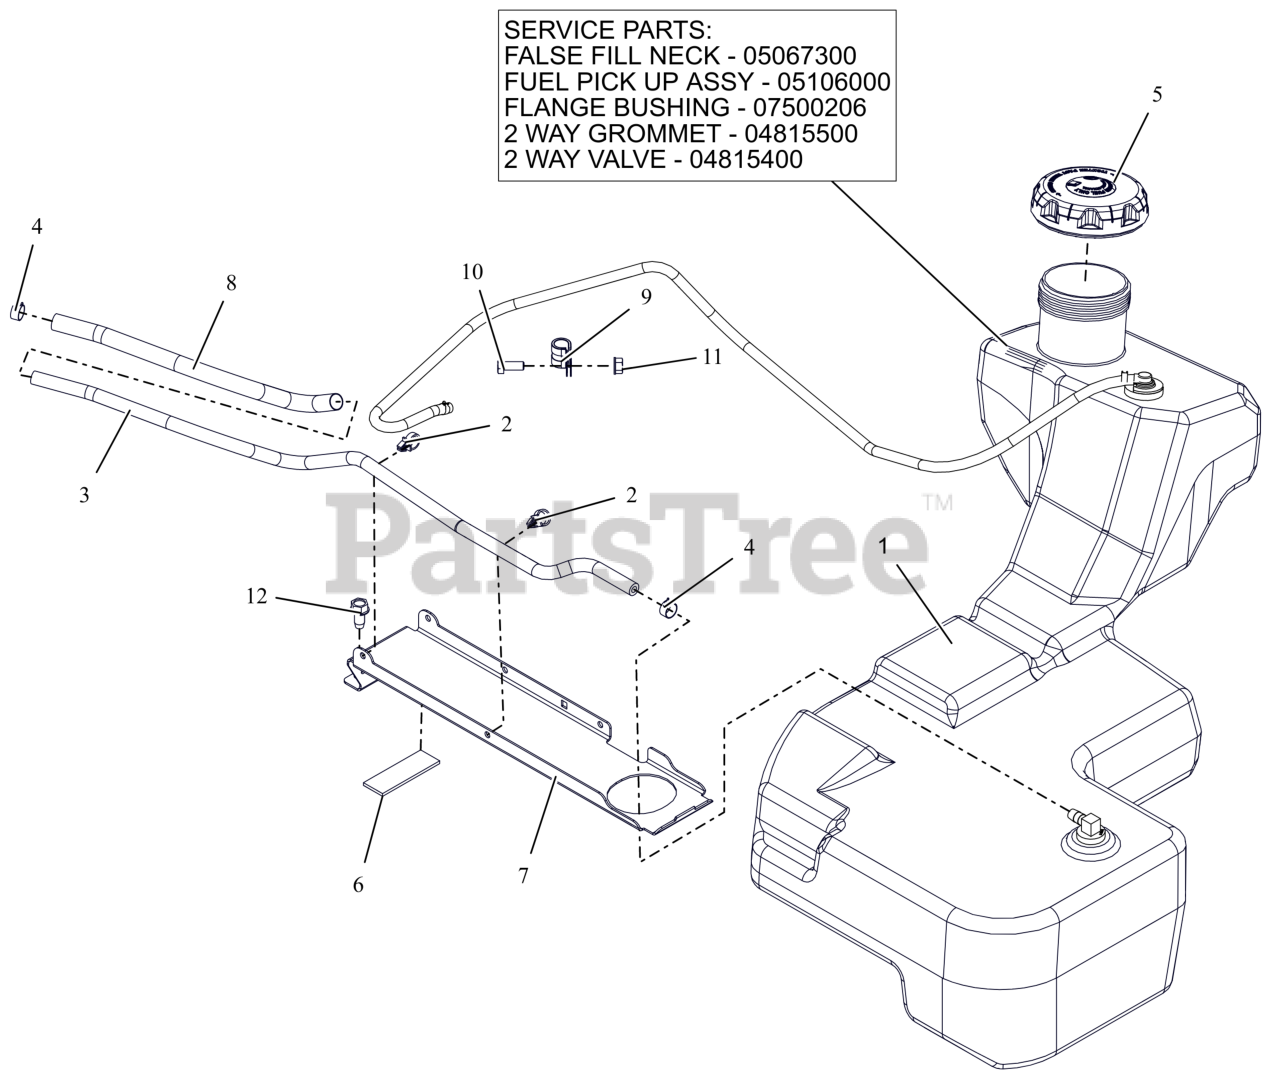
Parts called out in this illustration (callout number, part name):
1	ASM, FUEL TANK-HD
1	INSERT, FUEL NECK FALSE FILL
1	ASM, HD FUEL PICK-UP
1	BSHG-FLG .375X1.062X.625 NITR
1	GROMMET, 2-WAY
1	VALVE, 2-WAY
2	ROUTING CLIP (1/2" ID)
3	HOSE, .25 LOW-PERM BULK GAS
4	CLAMP, FUEL LINE
5	CAP, FUEL VENTIN AUTOLOCK
6	PAD,RBR 1.0"X3.0" W/ADHESIVE
7	BRKT, FUEL TANK HOLD DOWN
8	SLEEVE, THERMAL 12"
9	CLAMP, CUSHIONED STEEL
10	BLT,HEX .31-18X.75 G5 ZCC
11	NUT,LK-CTR-FLG .31-18 GF ZCC
12	SCR,TAP .375-16X.75 HWH TR ZCC
